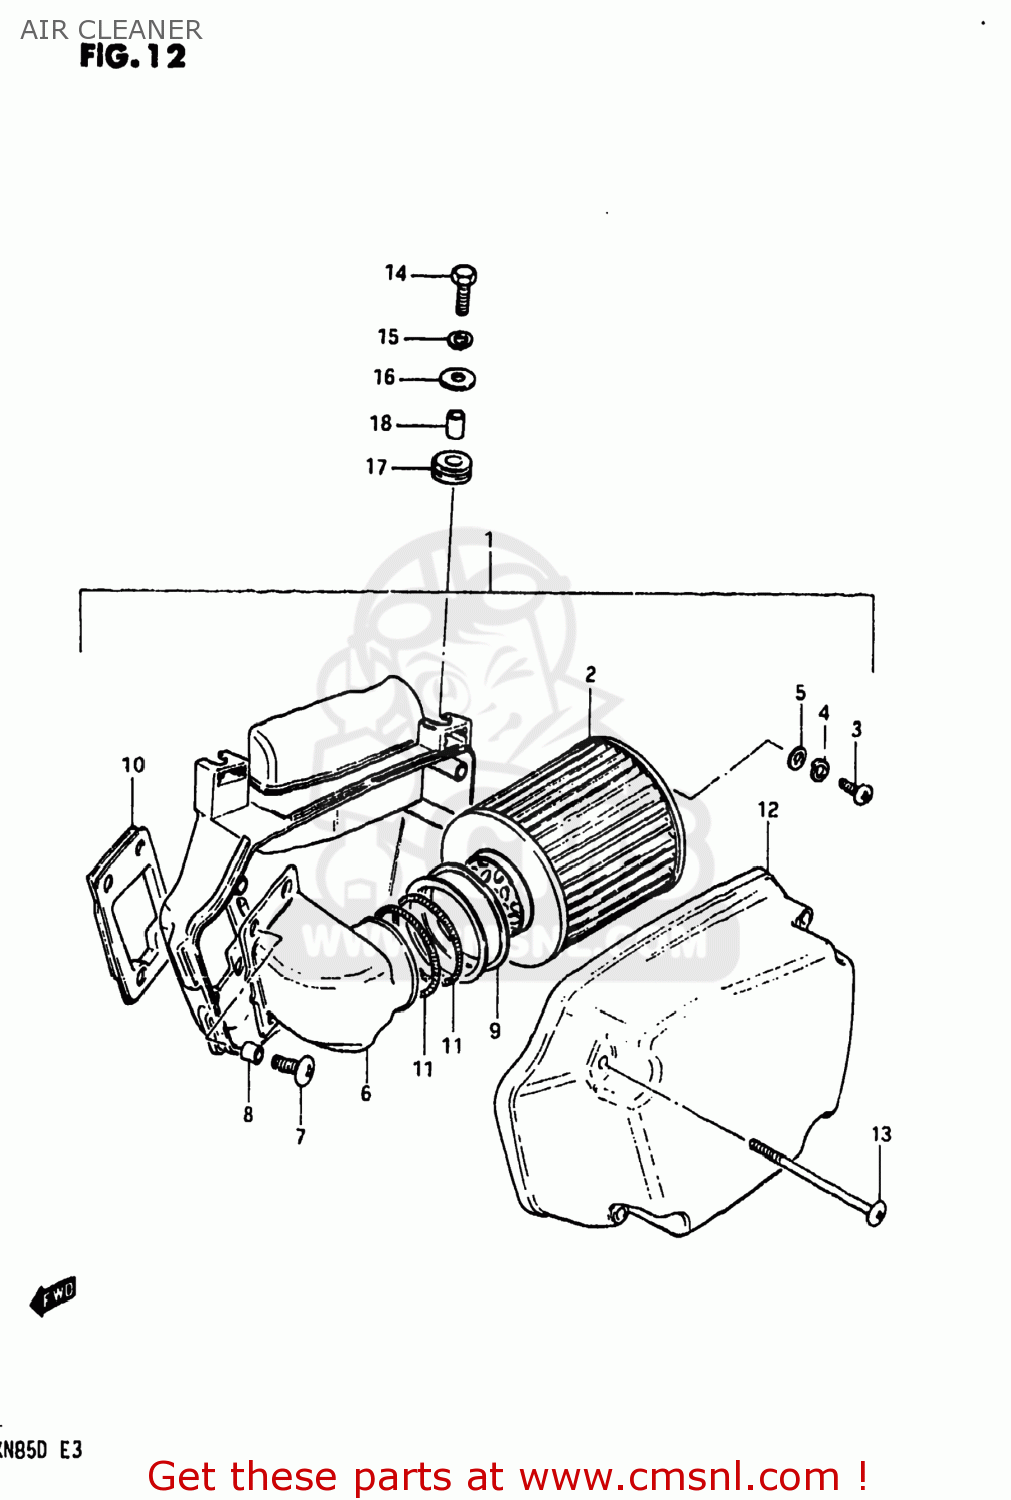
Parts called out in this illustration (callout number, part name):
1	CLEANER ASSEMBLY,AIR
2	FILTER
3	SCREW
4	LOCK WASHER
5	WASHER
6	TUBE,AIR CLEANER OUTLET
7	SCREW
8	COLLAR
9	JOINT
10	TUBE
11	SPRING,AIR CLEANER SIDE
12	CAP,AIR CLEANER
13	SCREW
14	BOLT 6X22
15	LOCK WASHER
16	WASHER
17	CUSHION
18	SPACER(6.1X9X7.5)
